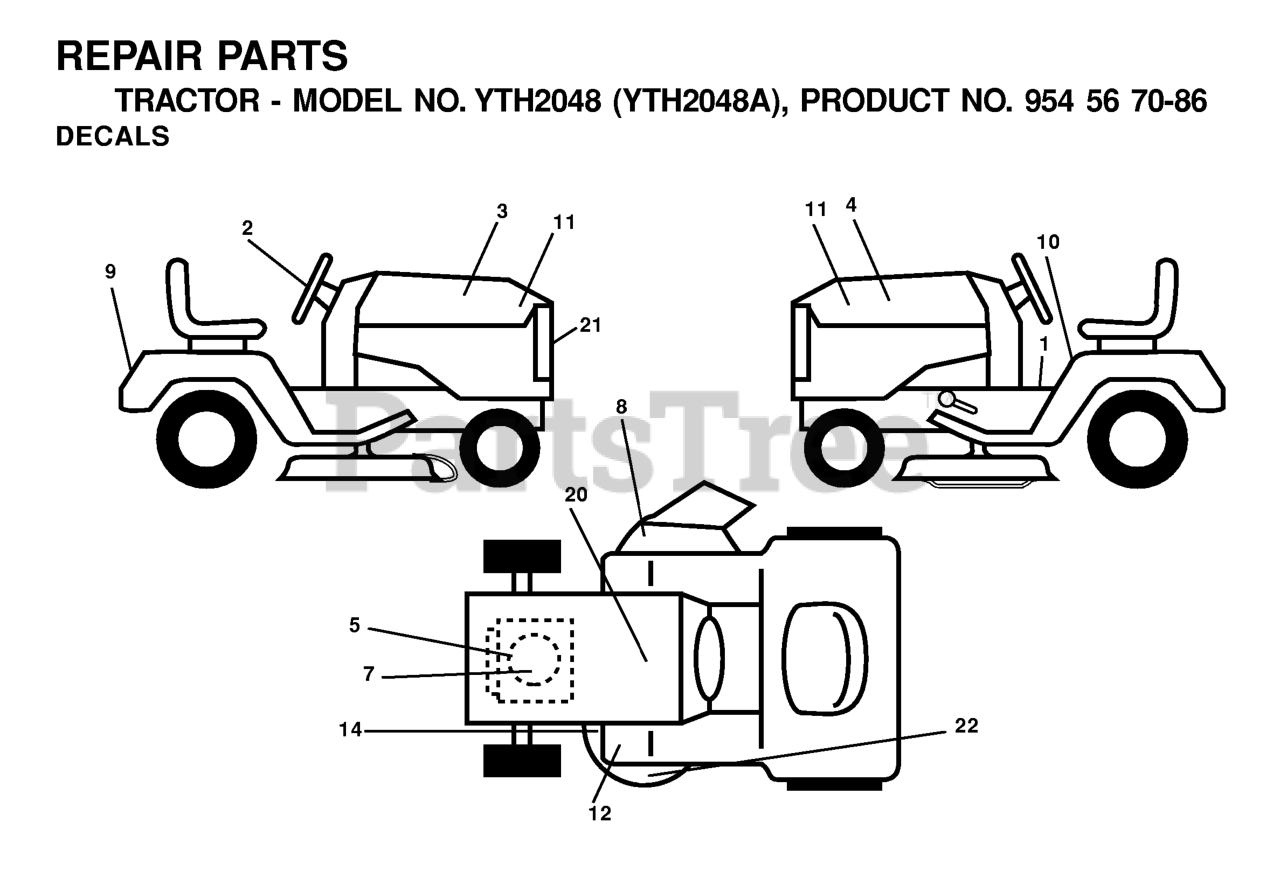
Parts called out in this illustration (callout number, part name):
2	DECAL.WHEEL.STEERING.HUSQ.PERM
8	DECAL.WARN.KEEP.HAND.AWAY
9	DECAL, FENDER
10	DECAL FENDER DANGER
14	DECAL V-BELT SCHEMATIC
20	DECAL BTRY SYMBOLS
21	DECAL.GRILLE.HUSQ
22	DECAL CLUTCH/BRAKE
